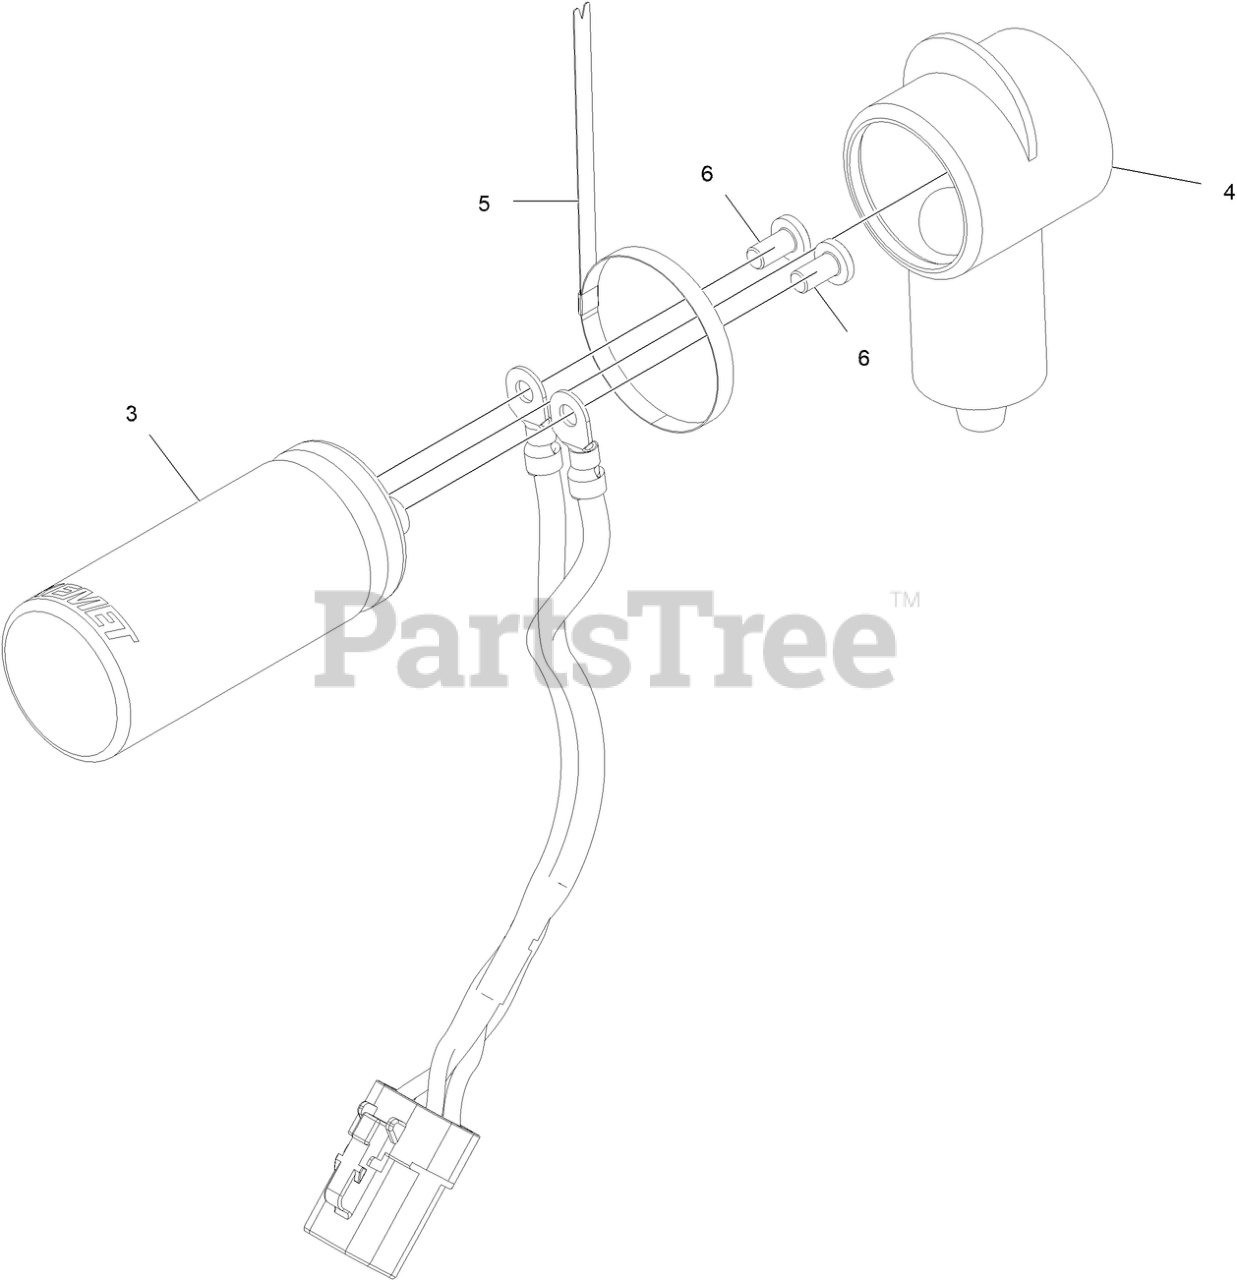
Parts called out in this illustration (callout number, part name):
3	Capacitor 36000Uf 40V
4	Boot-Capacitor
5	Tie-Stainless
